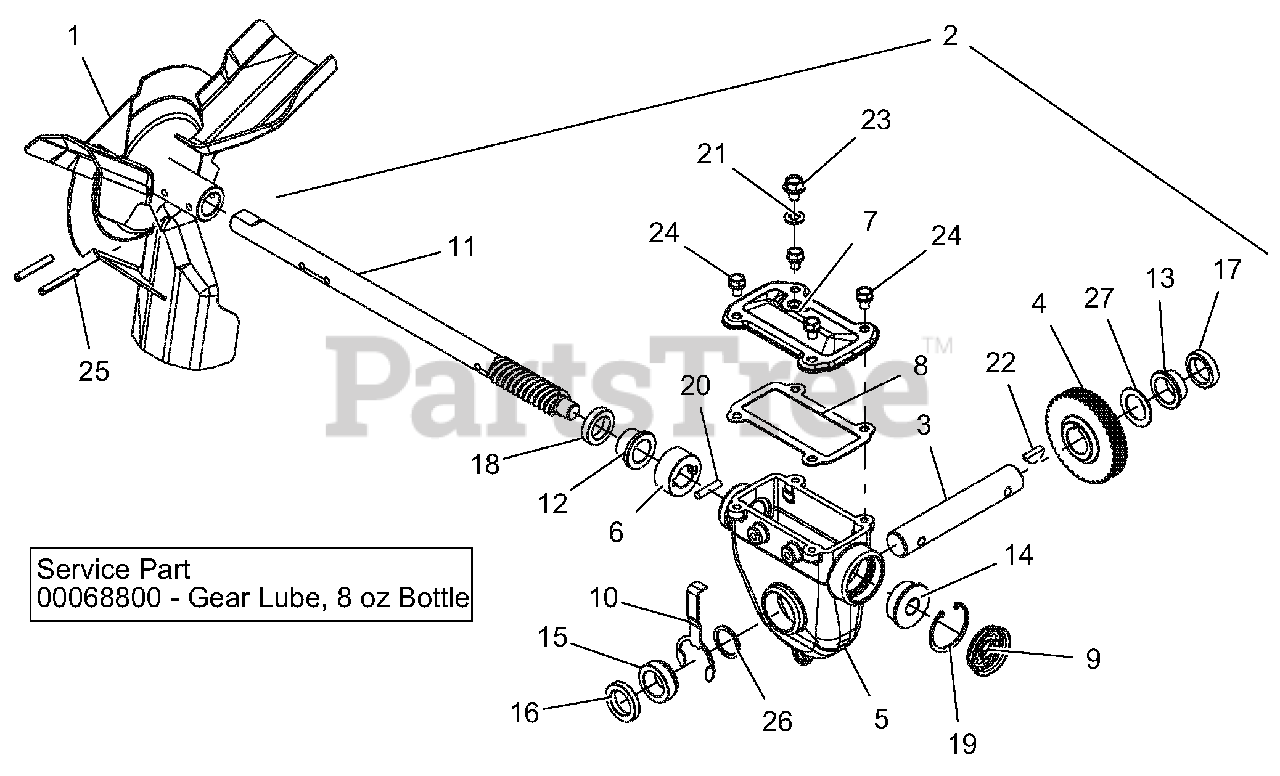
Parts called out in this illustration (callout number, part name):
1	IMPELLER, 3 BLADE-14"
2	GEAR CASE ASSY - DLX IRON
3	RAKE SHAFT, SHORT-COMMON
4	WORM SHAFT & GEAR
5	GEARCASE, LARGE MACHINED
6	THRUST COLLAR, .875"ID SLIPFIT
7	COVER, TOP - LARGE IRON
8	GASKET, TOP - LARGE GEARCASE
9	COVER, GEAR CASE 1.75"
10	BUSHING RETAINER, LARGE
11	WORM SHAFT & GEAR
12	BSHG-FLG .879X1.128X.75X1.45
13	BSHG-FLG 1.006X1.128X.555X1.45
14	BSHG-FLG .628X1.503X.58X1.725
15	BSHG-FLG LARGE, RIGHT
16	SEAL-OIL .999X1.500X.250 TBC29
17	SEAL-OIL .999X1.375X.312 TBC29
18	SEAL-OIL .873X1.375X.312 TBC29
19	RG-RTNG-INT 1.750X.062
20	PIN-STR .250X1.12 6150
21	WSHR-BND-SEAL .38X.75X.11 GALV
22	KEY-WDRF .25X.875 HRD #A
23	@SCR-ROLOK .38-16X.50 HWH YWZC
24	BOLT, SEMS .31-18X.50 GR5 YWZC
25	PIN-ROLL .250X1.75
26	WSHR-FL-STL 1.010X1.250X.068YZ
27	WSHR-FL-STL 1.010X1.505X.062YZ
